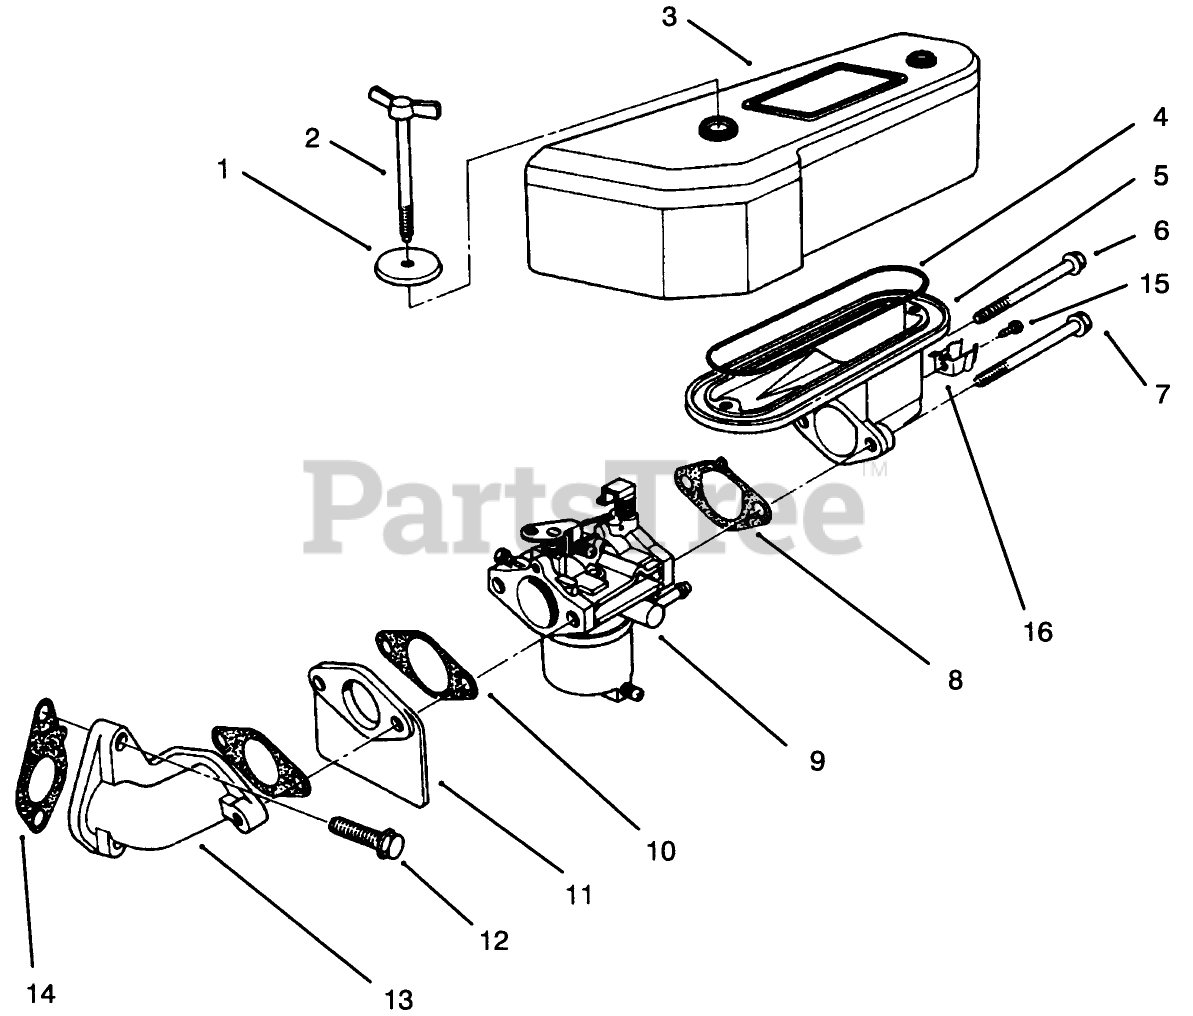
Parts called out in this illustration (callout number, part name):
3	Air Filter Assy (includes items 32, 33, 34 35)
5	Pipe-Intake
9	Carburetor ASM
11	Insulator
12	Bolt-Flanged (8X25)
13	Pipe-Intake
